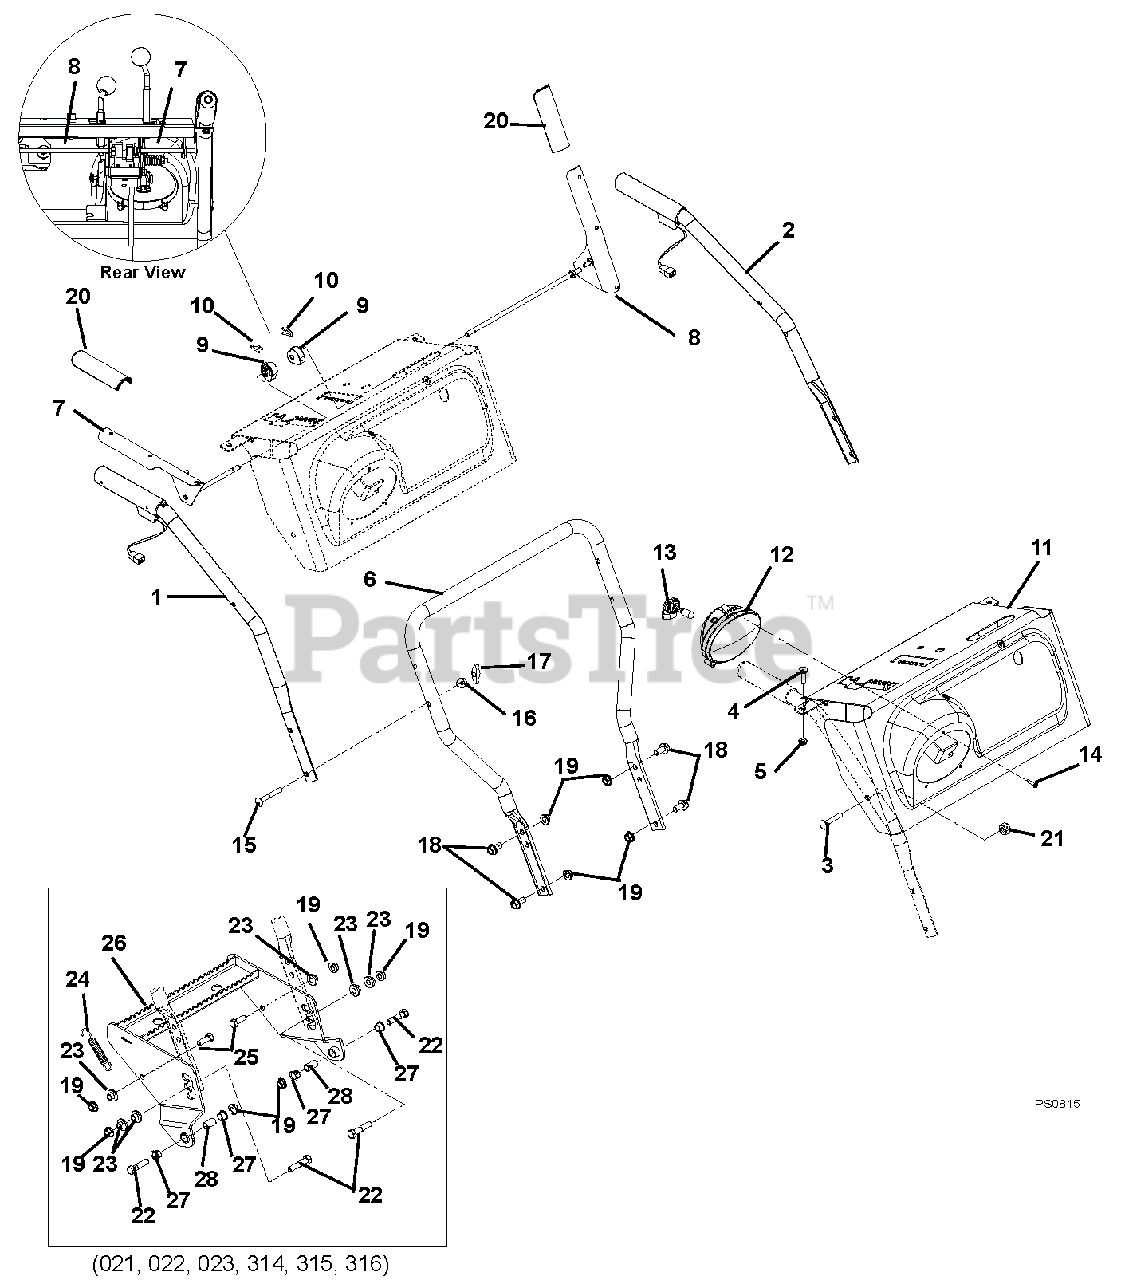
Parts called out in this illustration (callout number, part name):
1	HANDLEBAR, UPPER RH-W/HW
2	HANDLEBAR, UPPER LH-W/HW
3	@BLT-RDHDSQNK .31-18X1.75 G5YZ
4	BLT-RDHDXLSQNK.25-20X1.25 G5ZC
5	@NUT-LK-CTR .25-20 YWZC
6	HANDLEBAR, LOWER
7	LEVER, RH-ATTACHMENT
8	LEVER, LH-TRACTION
9	CAM, INTERLOCK
10	PIN, SPRING CLIP
11	PANEL-W/CONTROL HW DECAL
11	PANEL-W/CONTROL 12V DECAL
11	PANEL-W/CONTROL BRUSH DECAL
12	LIGHT, HALOGEN ASSY.
13	BULB, LIGHT-HALOGEN 20W
14	SCR-TAP 10-16X.75 HI-LO PPH
15	@BLT-RDHDSQNK .31-18X2.25 G5YZ
16	SPACER, HANDLEBAR
17	KNOB - WING .312-18 UNC
18	BLT-SERHFWH .38-16X.75 YWZC
19	@NUT-LK-TOP-FLG .38-16 YWZC
20	GRIP, CLUTCH LEVER, LH AND RH
21	@NUT-LK-CTR .31-18 YWZC
22	@BLT-HEX .38-16X1.75 GR5 YWZC
23	BSHG-FLG .385X.500X.875X.406
24	SG-TENS .080X.470X4.88 WLD 30
25	@BLT-HEX .38-16X1.00 GR5 YWZC
26	ADJUSTER, HEIGHT-FOOT
27	BUSHING, POLYLINER-.50 SPLIT
28	SPACER, TUBE .384X.500X.860
